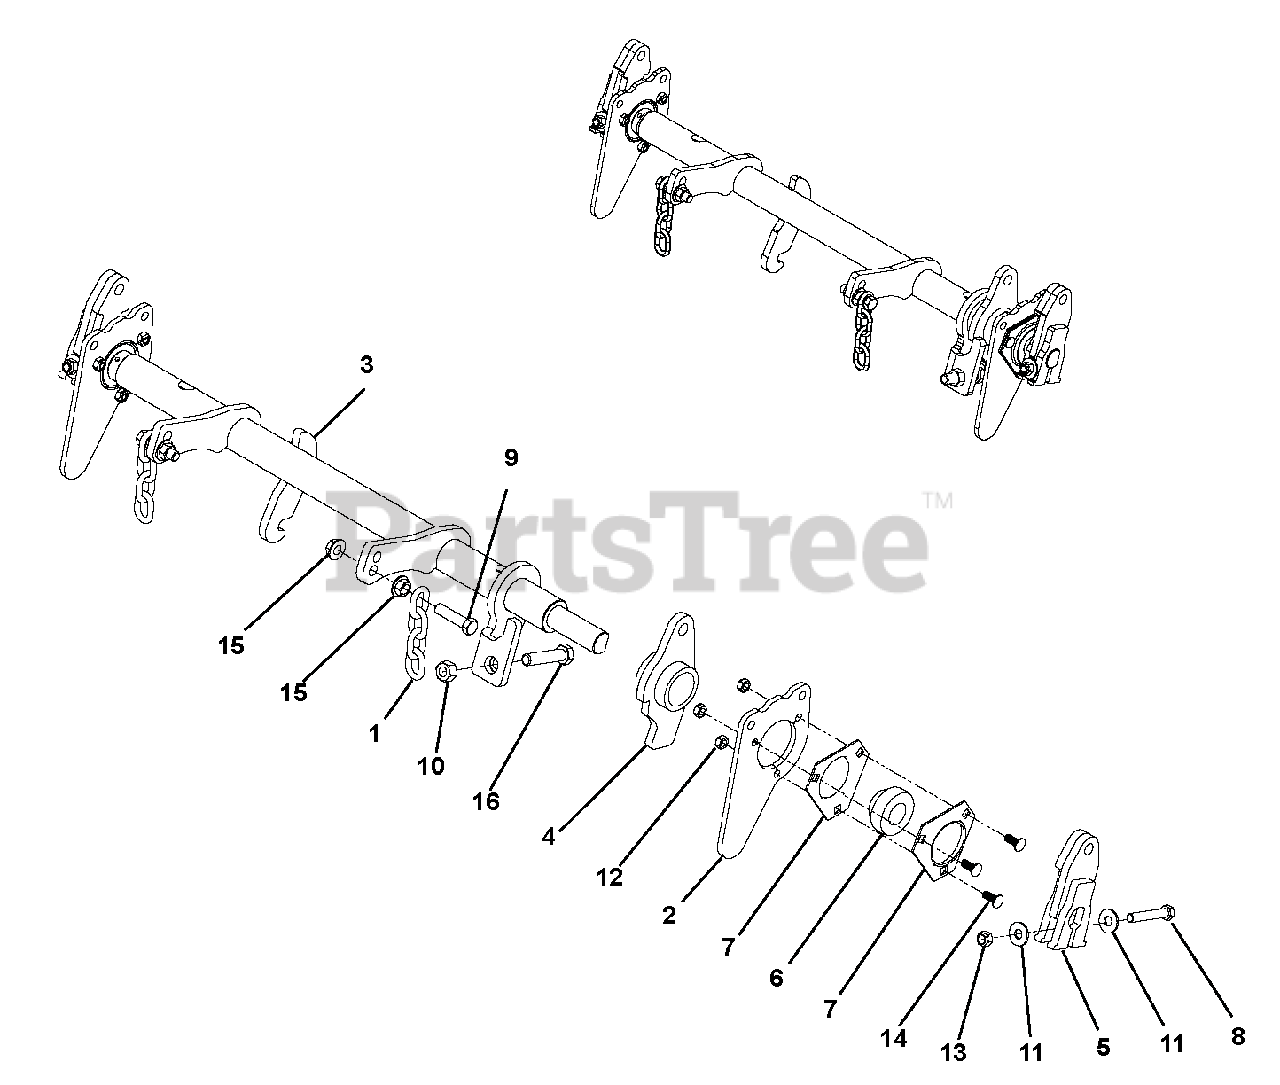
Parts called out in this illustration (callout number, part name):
1	CHAIN, 4 LINKS 1/4" GR70 Y
2	BALL BEARING PLATE
3	WLDT, CENTER LIFT
4	WLDT, HOC ROTATION ADJUSTMENT
5	WLDT, FRONT PIVOT CLAMP
6	BEARING, SET SCREW COLLAR
7	FLANGE, BEARING 52MM-3T-YZP
8	@BLT-HEX .38-16X2.25 GR5 YWZC
9	@BLT-HEX .44-14X1.75 GR5 YWZC
10	@NUT-HEX .50-13 YWZC
11	@WSHR-FL-STL.438X1.00X.083 YWZ
12	NUT-CROWN .312-18 YWZC
13	NUT-LK-FLG .375-16 PL
14	@BLT-RDHDSQNK .31-18X.75 G5YZ
15	NUT-FLANGED WHIZ .438-14 YWZC
16	BOLT, 1/2-13X2.25 HEX 5 FLTD Y
